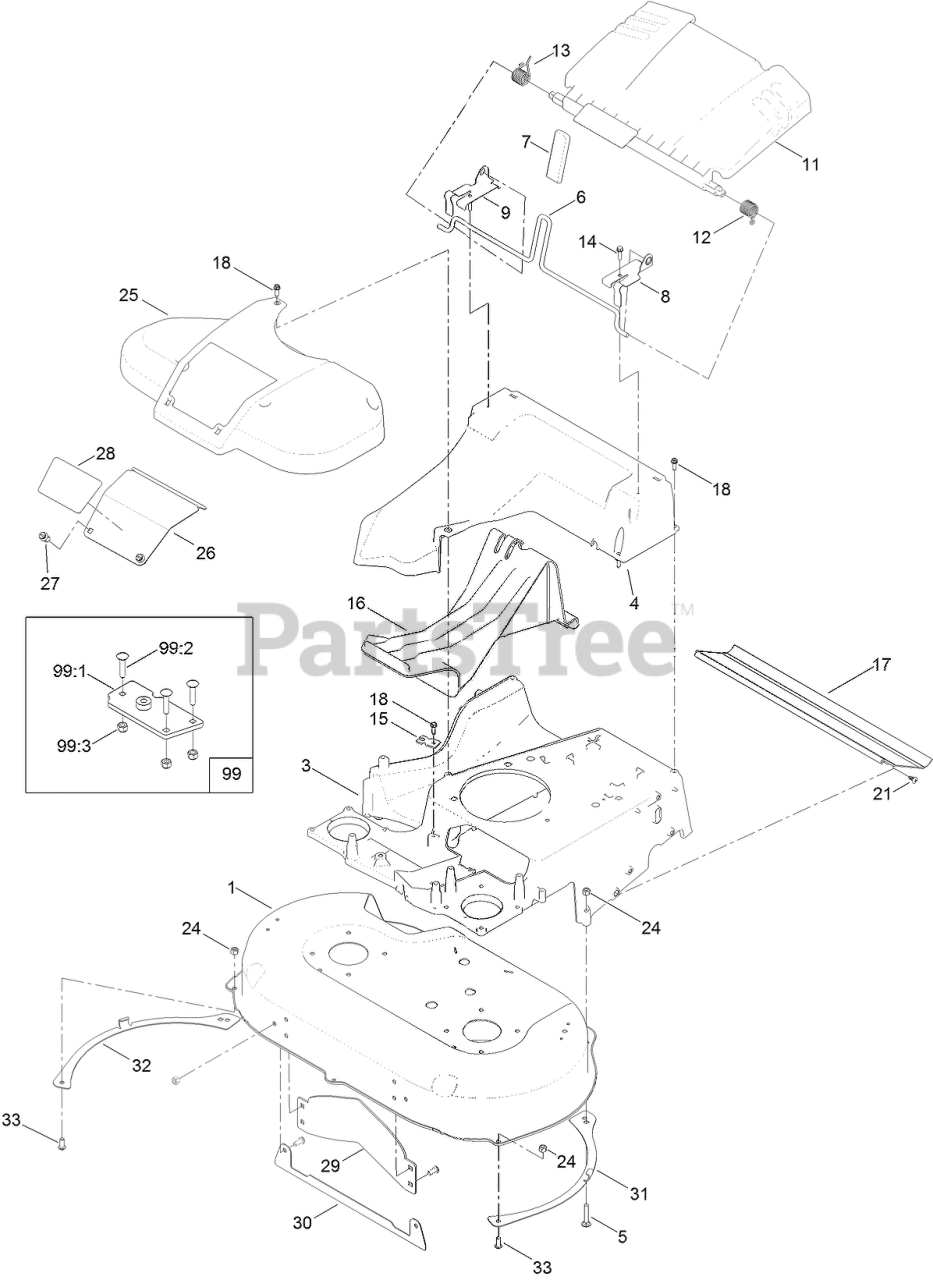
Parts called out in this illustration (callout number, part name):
1	HOUSING ASM
4	CHUTE
5	SCREW-CARR
6	ROD-RELEASE, HANDLE
7	GRIP-LEVER
8	BRACKET-DOOR, LH
9	BRACKET-DOOR, RH
11	REAR DEFLECTOR ASM
12	SPRING-TORSION
13	SPRING-TORSION
14	SCREW-HWH
15	BRACKET-CABLE, TRACTION
16	PLUG-MULCH
17	SHIELD-TRAILING
18	SCREW-HWHTF
21	SCREW-PTH
24	NUT-LOCK, NI
25	COVER-BELT
26	DOOR-ACCESS
27	FASTENER
28	DECAL-ACCESS PANEL
29	BAFFLE-CONTROL
30	PLATE-DECK
33	SCREW-HSBH
99	FRAME PLATE KIT
99:1	PLATE-FRAME
99:2	SCREW-CARR
99:3	NUT-LOCK, NI
